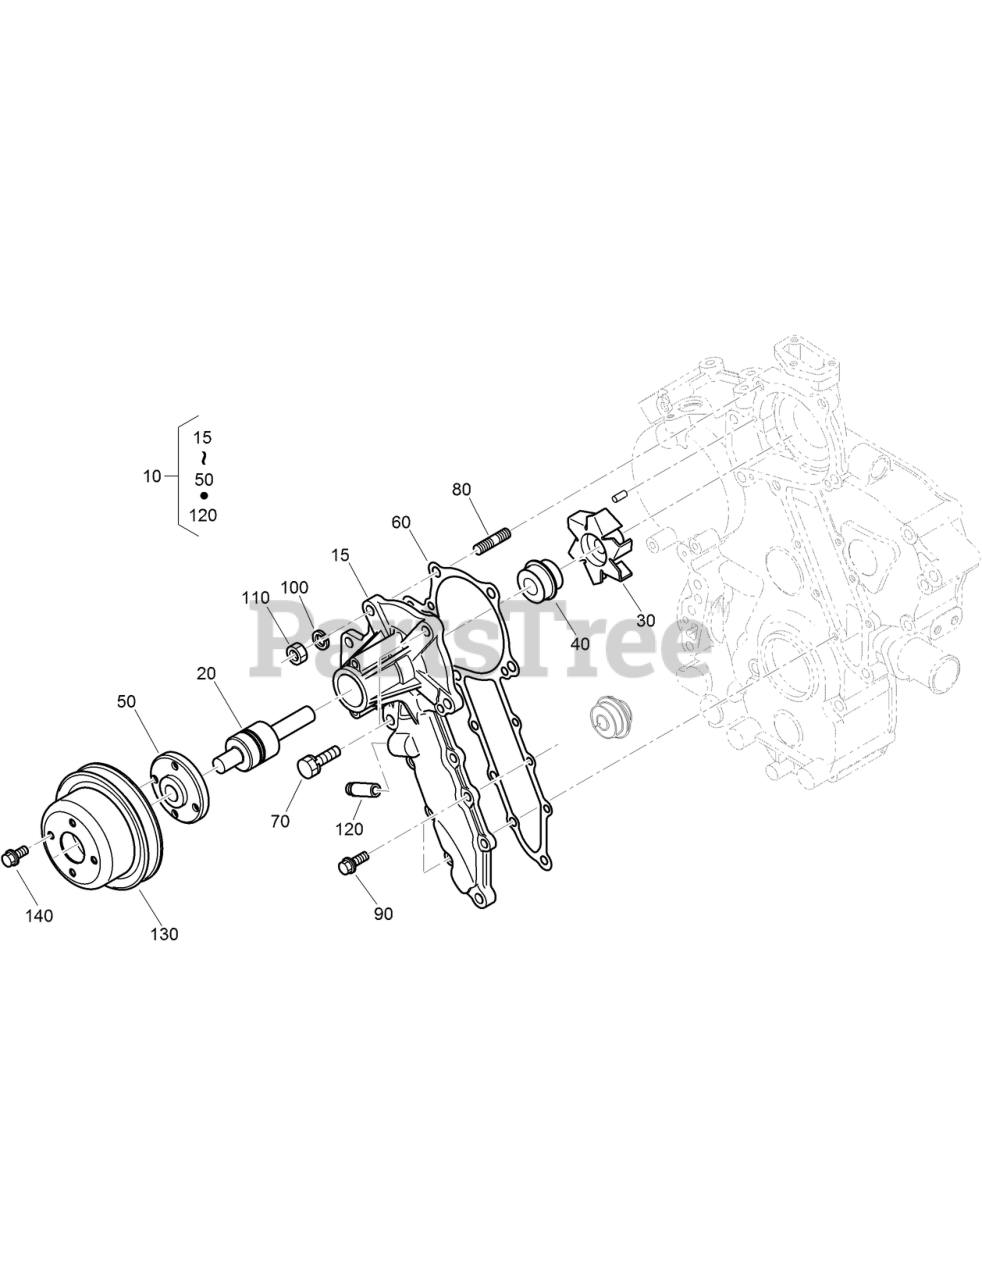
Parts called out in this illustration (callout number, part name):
10	WATER PUMP ASM
15	BODY-PUMP, WATER
20	BEARING
30	IMPELLER
40	MECHANICAL SEAL ASM
50	FLANGE-SHAFT, WATER PUMP
60	GASKET-PUMP, WATER
90	BOLT-FLANGE
100	WASHER-SPRING, LOCK
120	PIPE-RETURN, WATER
130	PULLEY-FAN
140	BOLT-FLANGE
